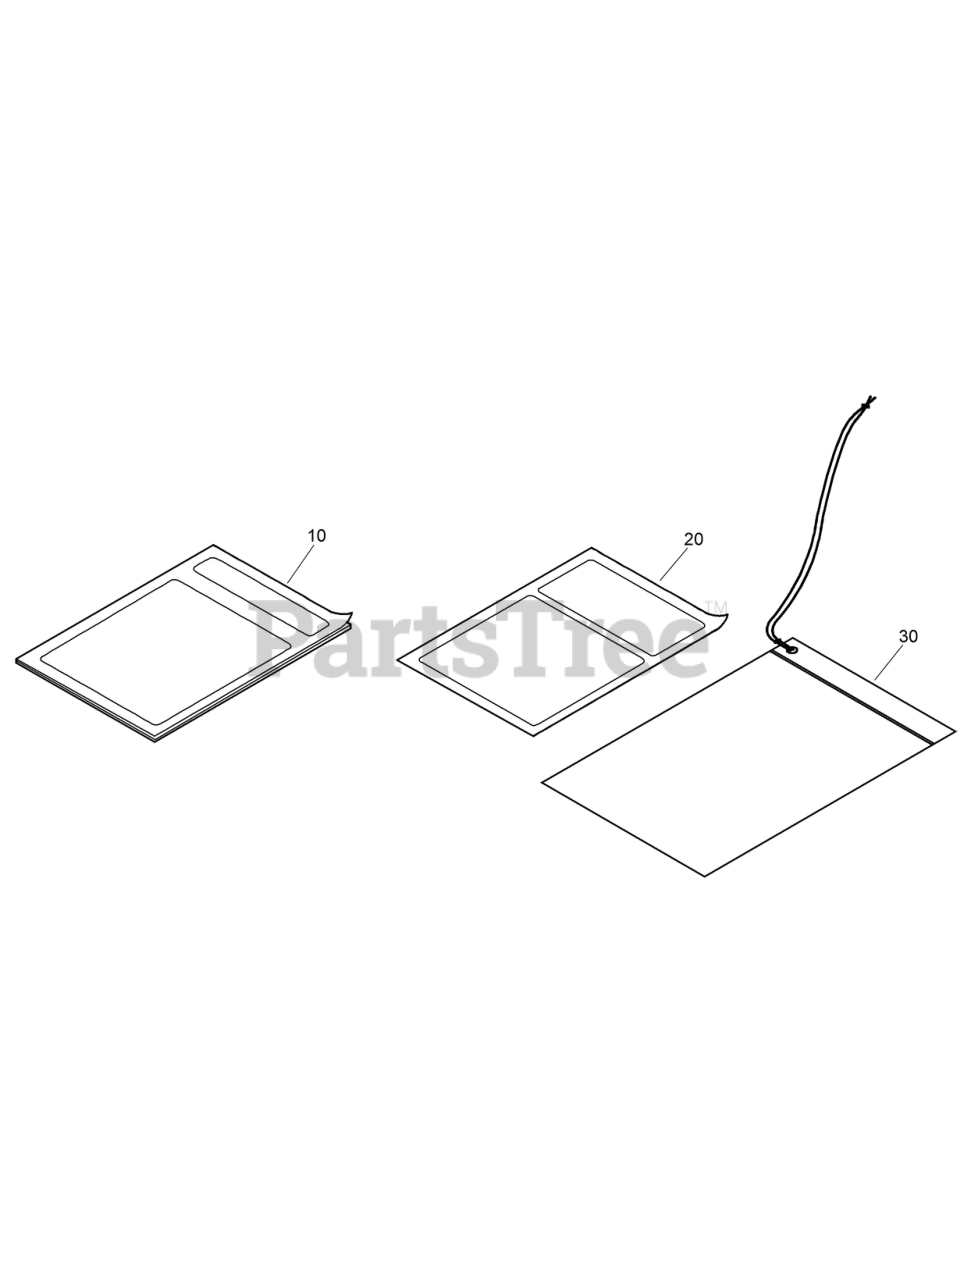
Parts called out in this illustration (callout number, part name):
10	MANUAL-OPERATOR
20	MANUAL-INSTRUCTION
30	BAG-PLASTIC
